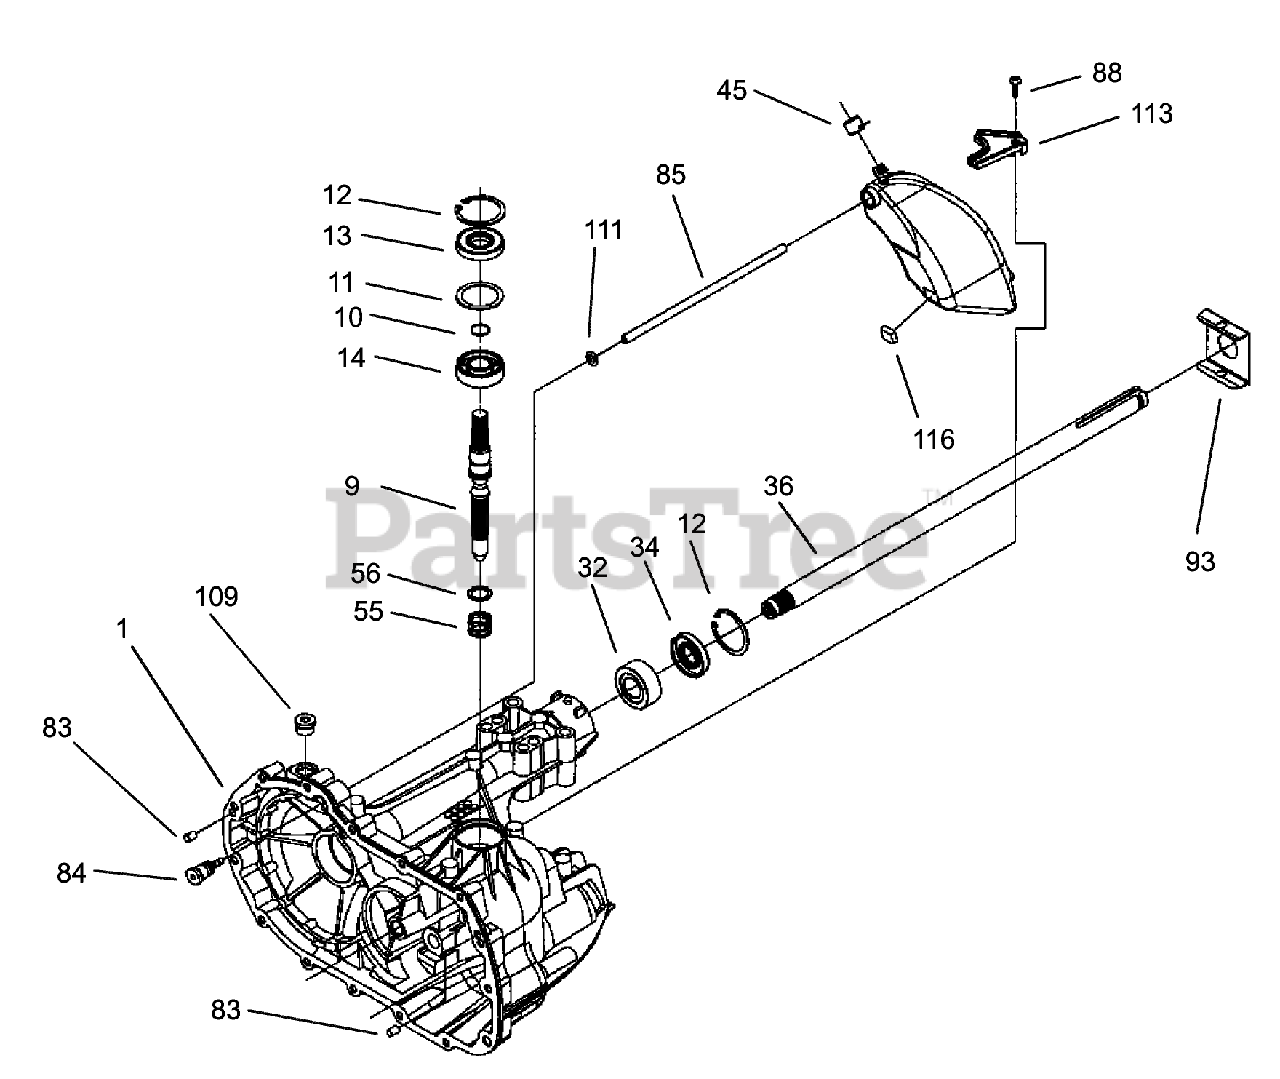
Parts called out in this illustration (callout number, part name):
1	MAIN HOUSING ASM
9	SHAFT-INPUT
10	RING-RETAINING
11	SPACER
12	RING-RETAINING
13	SEAL-LIP
14	BEARING-BALL
32	BEARING-SLEEVE, OUTBOARD
34	SEAL-LIP
36	SHAFT-AXLE, LH
55	SPRING-BLOCK
56	WASHER-THRUST
84	FITTING-SAE
85	HOSE-EXPANSION, TANK
87	CAP-VENT
88	BOLT-TAPPING, SELF
93	CLIP-SPRING
111	O-RING
113	BRACKET-SUPPORT
116	SPONGE-SILICONE
